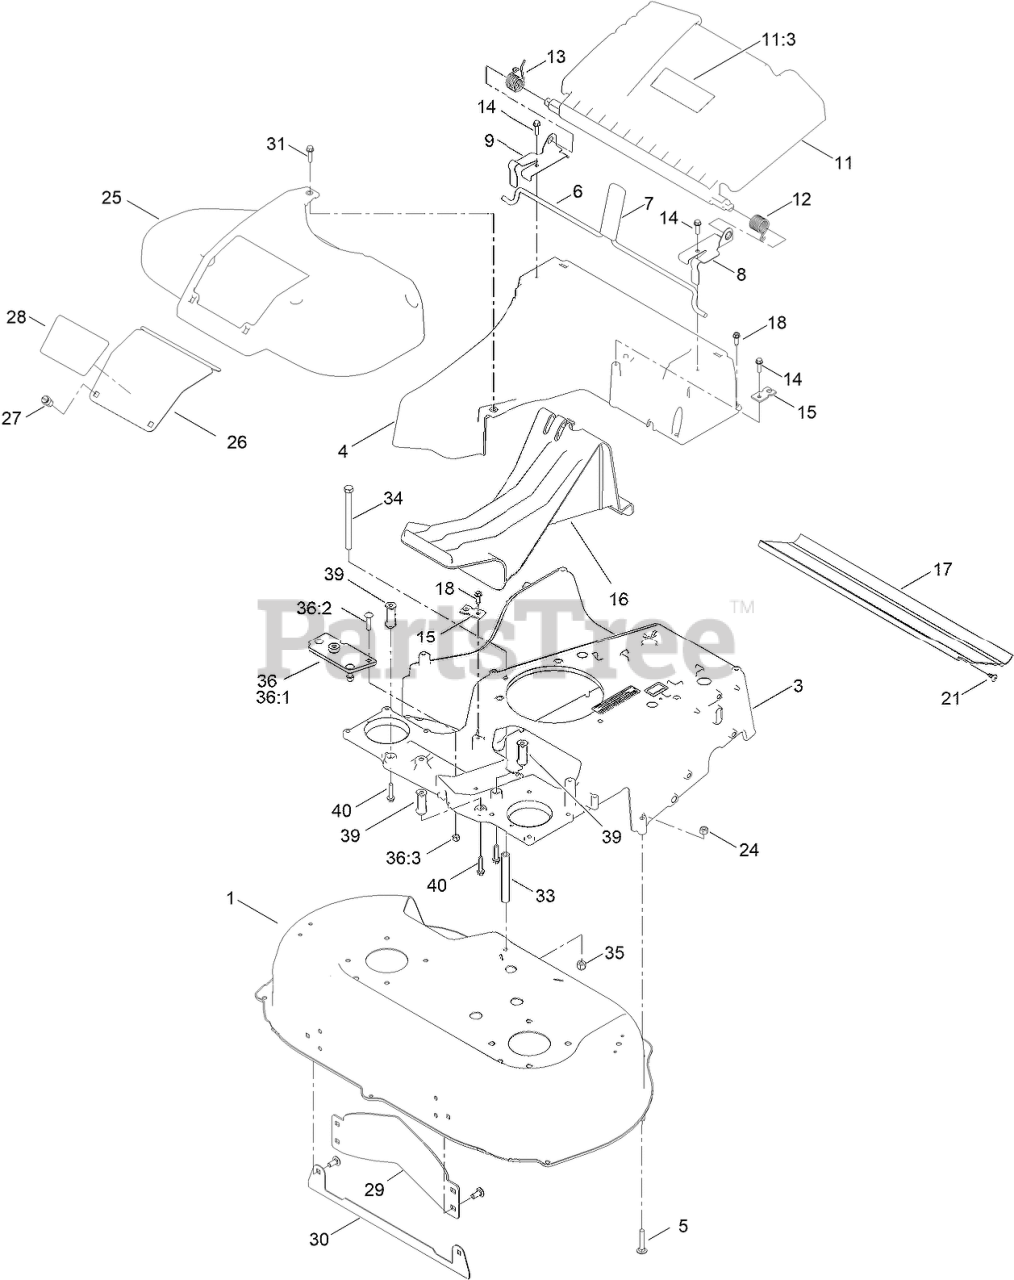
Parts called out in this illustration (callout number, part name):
1	HOUSING ASM
3	FRAME-30"
5	BOLT-CAR
6	ROD-RELEASE, HANDLE
7	GRIP-LEVER
8	BRACKET-DOOR, LH
9	BRACKET-DOOR, RH
11	REAR DEFLECTOR ASM
11:3	DECAL-WARNING
12	SPRING-TORSION
13	SPRING-TORSION
14	SCREW-PLASTITE, HWH
15	BRACKET-CABLE, TRACTION
16	PLUG-MULCH
17	SHIELD-TRAILING
18	SCREW-HWHTF
21	SCREW-THD
24	NUT-HEX
25	COVER-BELT
26	DOOR-ACCESS
27	FASTENER
28	DECAL-ACCESS PANEL
29	BAFFLE-CONTROL
30	PLATE-DECK
31	SCREW-HWHTF
33	SPACER-SHIELD
34	SCREW-HH
35	NUT-HEX
36	FRAME PLATE KIT
36:1	PLATE-FRAME
36:2	SCREW-CARR
36:3	NUT-LOCK, NI
39	SPACER-FRAME, 30 IN.
40	SCREW-HWHTF
